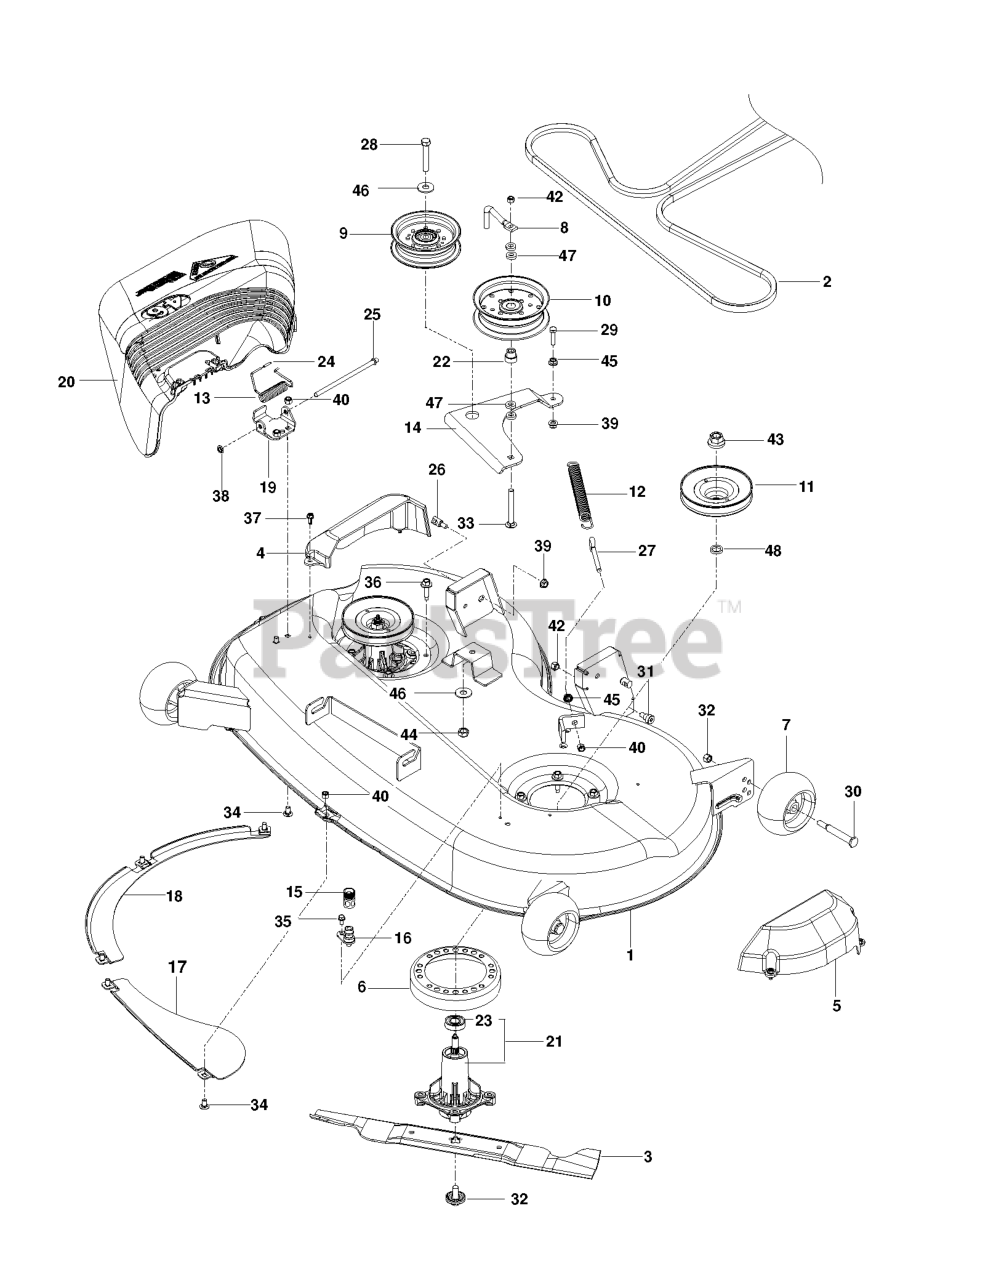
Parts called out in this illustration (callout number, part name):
1	DECK W/DECALS - RZ46
3	BLADE.MOWER.46".HI.LIFT
4	COVER.MANDREL.RH.46"
5	COVER.MANDREL.LH.46"
6	STRIPPER-ROUND-UNIVERSAL
7	GAUGE WHEEL
8	BELT KEEPER 5"
9	PULLEY.IDLER.MWR.STATI.LH
10	PULLEY, IDLER
11	RP.PULLEY, DECK
12	SPRING, DECK BELT
13	TORSION SPRING
14	ARM, IDLER BLK
15	COUPLING.QUICK CONNECT
16	PORT.WASHOUT
17	BAFFLE CENTER FRONT
18	BAFFLE FRONT RH
19	BRKT.DEFLECTOR.38"2005+
20	SHIELD.DEFLECTOR.MOWER.46"BLAC
21	CUTTER HOUSING
22	IDLER BUSHING
24	CAP-SLEEVE
25	ROD, HINGE
26	STUD.FASTNER.W/ANTI-ROTATE
27	EYE BOLT 5/16 X 3.50
28	BOLT 7/16-14 X 2-1/2 GR 5 ZD
29	HCS 5/16C X 1 1/4
30	SHOULDER BOLT 1/2X2-5/8 ZD SPE
31	SB 3/8-16 X 3/8 SKT HD ZD
32	BOLT.WASHER.ASM.7/16-2
33	CARRIAGE BOLT 3/8-16 X
34	BOLT 5/16C X 3/4" CARRIAGE
35	SCREW #10 X 1/2 SELF TAPPING
36	WASHER HEAD SCREW
37	SCREW- 1/4-20 X 5/8
38	PUSH NUT
39	5/16-18 NYLOC FLANGE NUT
40	NUT 5/16 NYLOC
41	NUT 3/8-16 NYLOC
42	NUT HEX 3/8-16 NYLON, THIN
43	LOCKNUT - 9/16
44	7/16-14 HEX NUT W/NYL RING ZD
45	NUT 5/16C WHIZ
46	WASHER 7/16 FLAT ZD
47	WASHER 3/8 X 3/4 X .187 TK
48	WASHER-SPACER
